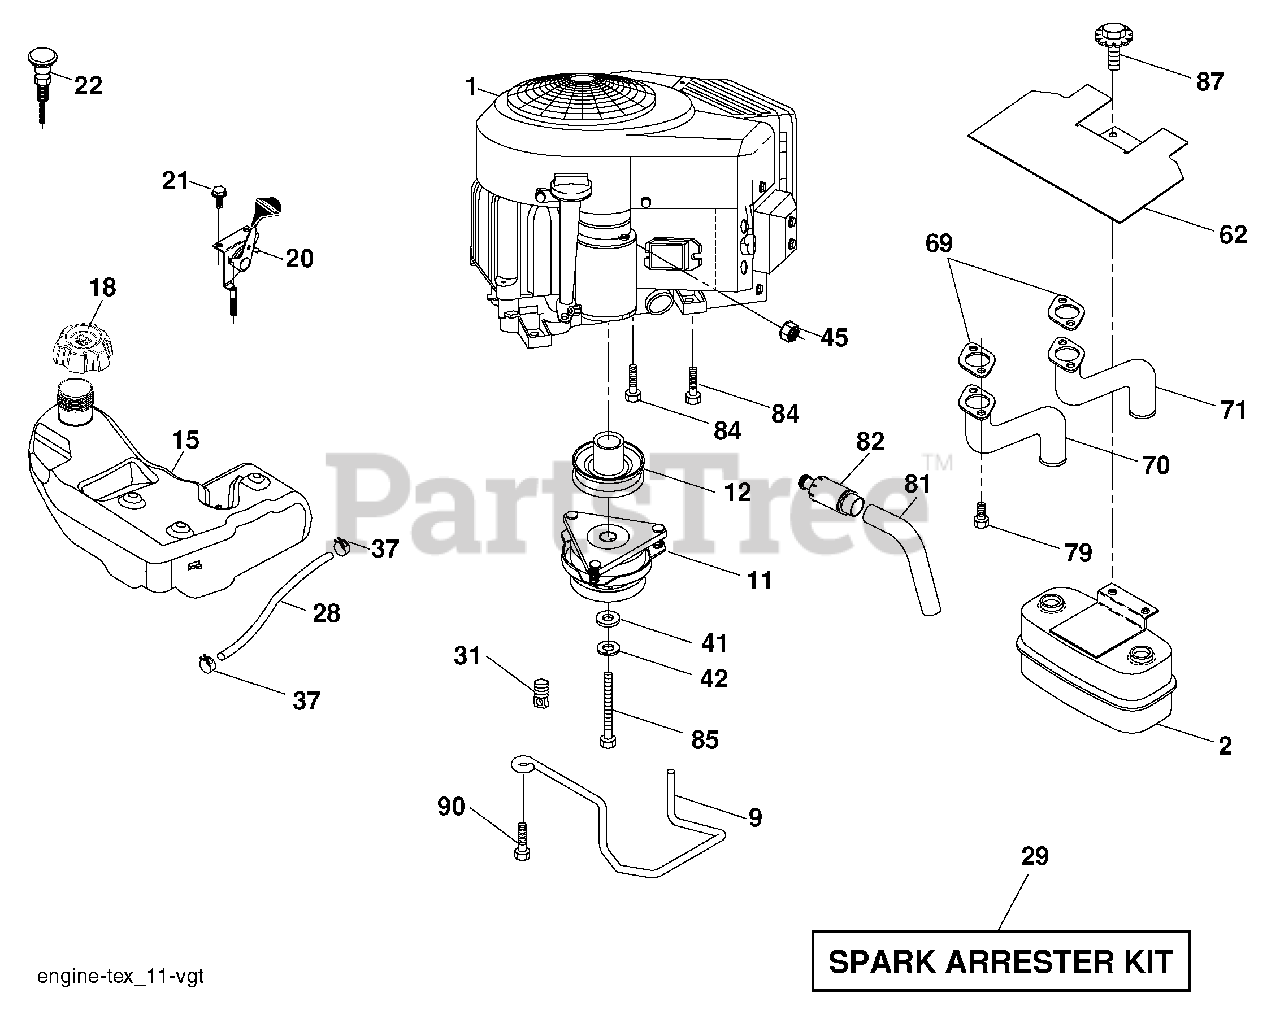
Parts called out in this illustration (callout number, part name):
2	Muffler
9	Keeper Belt Engine
11	Clutch Electric
12	Pulley Engine
15	Tank Fuel 3.0
18	Cap Asm
20	Control Throttle
21	Screw 10 x 3/4 Single Lead-Hex
22	Control Choke
28	Fuel Line
29	Spark Arrester Kit
31	Clip Push-In Hinged
37	Clamp Hose
41	Washer 1-1/2 OD x 15/32 ID x .250
42	Washer Lock 7/16
45	Nut Keps Hex 1/4-20 unc
62	Shield Heat Muffler
69	Gasket
70	Exhaust Tube RH
71	Exhaust Tube LH
79	Screw Socket Head 5/16-18 x 1
81	Tube Drain Oil Easy
82	Plug Drain Oil
84	Screw 3/8-16 x 1-1/4
85	Bolt Hex 7/16-20 x 4 x 1/4 5 Ga.
87	Bolt 5/16-18 x 3/4
90	Screw 3/8-16 x 1
